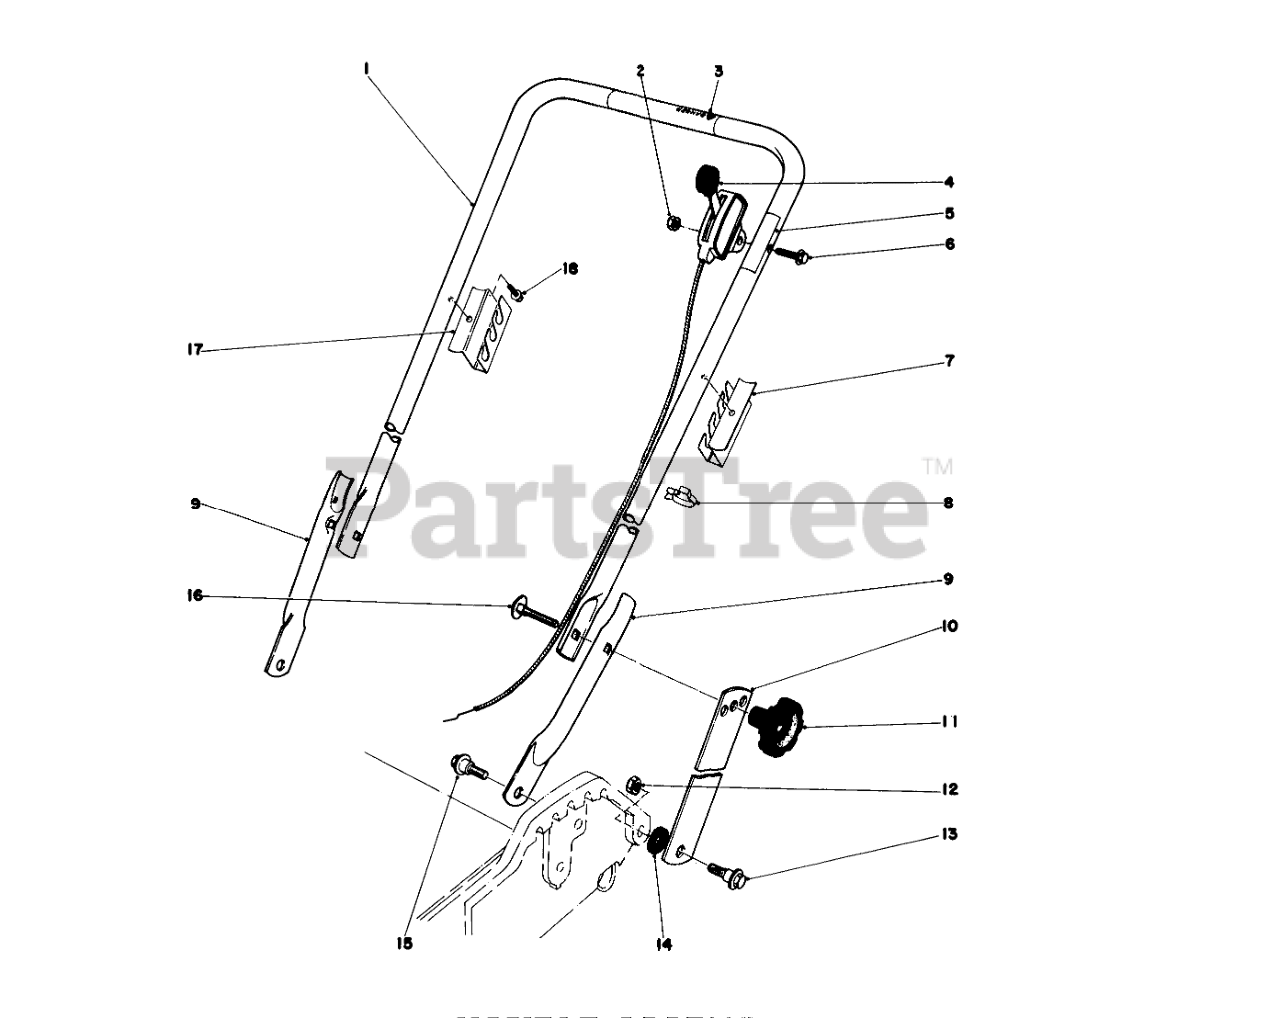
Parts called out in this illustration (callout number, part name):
1	Handle-Upper
2	NUT-LOCK
3	Decal
4	Throttle Control
5	Decal-Throttle
6	SCREW-HH
7	SUPPORT BAG LH
8	BOWDEN CLIP
9	Hand-Lower
10	18" HANDLE LATCH
12	Nut
13	SCREW-SHOULDER
14	SPACER
15	SCREW-SHOULDER
16	SCREW-HANDLE
17	SUPPORT BAG RH
18	SCREW-HWHTF
